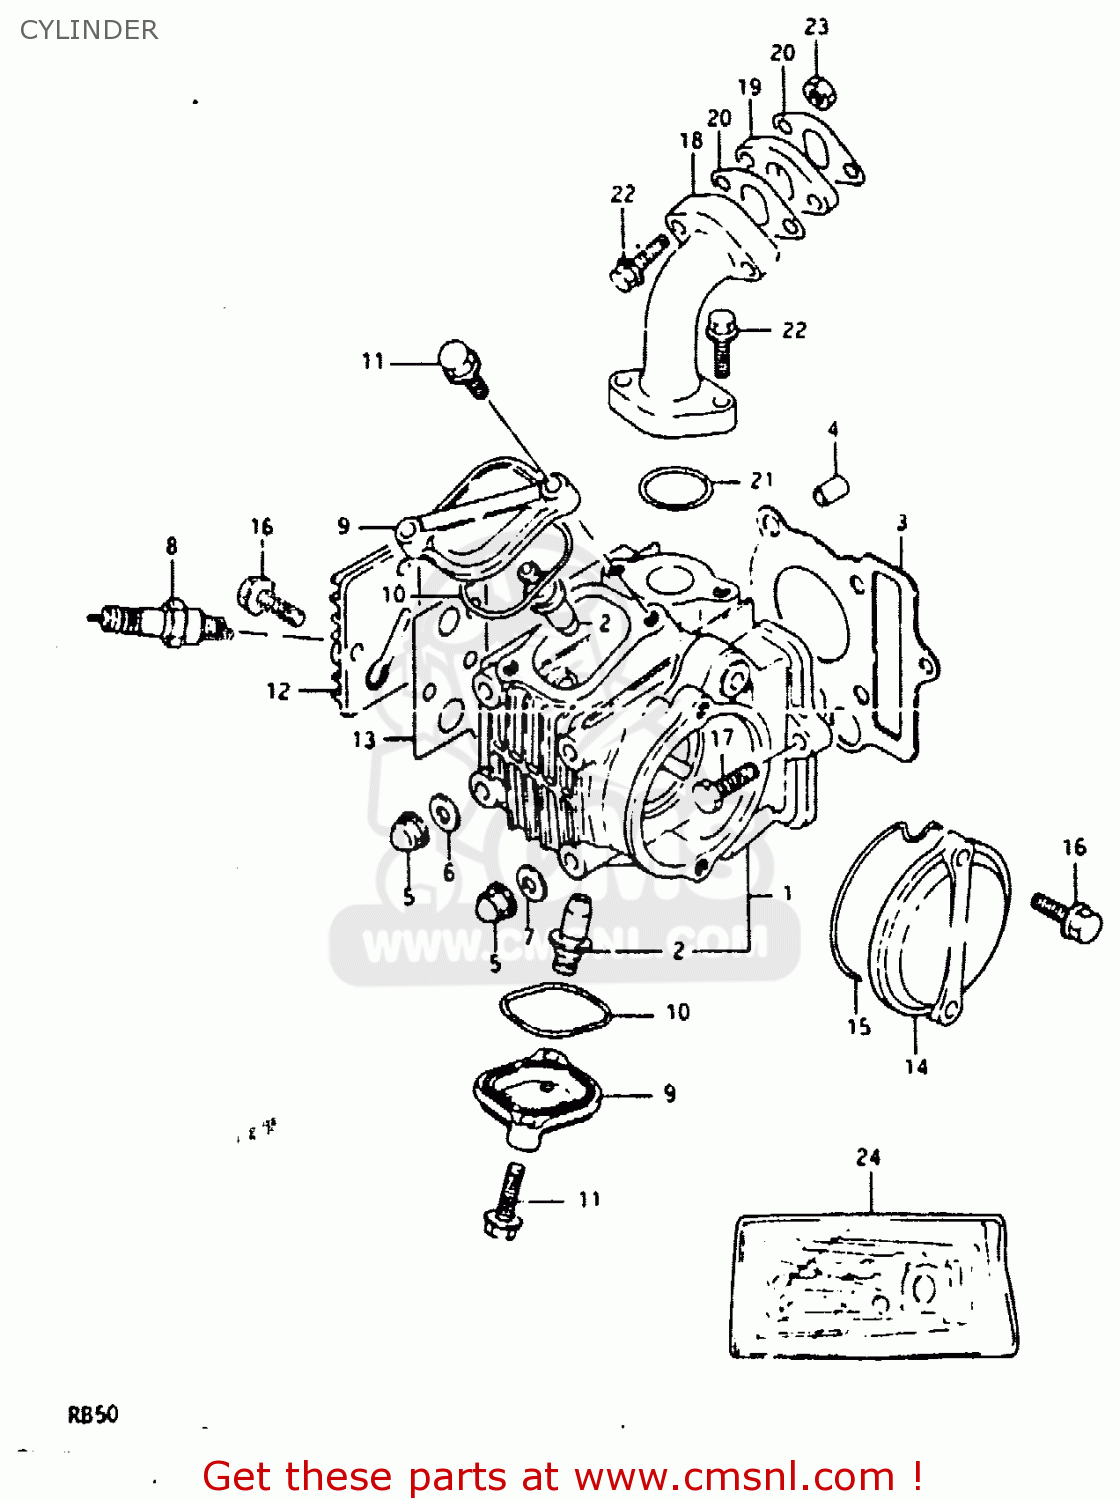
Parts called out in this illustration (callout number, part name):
1	HEAD,CYLINDER
2	GUIDE,VALVE
3	GASKET,CYLINDER HEAD (NAS)
4	PIN(6.2X8X11)
5	NUT
6	GASKET(6.5X13X2.3) (NAS)
7	WASHER (6.5X13X2.3)
8	SPARK PLUG C6HA
10	O RING(D:2.4,ID:33.6X48.6)
11	BOLT
12	COVER,CYLINDER HEAD,R
13	PLATE
14	COVER,CYLINDER HEAD,L
15	O RING(D:2.4,ID:73.5)
16	BOLT,REAR
17	BOLT
18	PIPE,INTAKE
19	INSULATOR,CARBURETOR
20	GASKET,CARBURETOR (ASB)
21	O-RING (D:2.4 ID:23.7)
22	BOLT
23	NUT 6MM
24	GASKET SET
